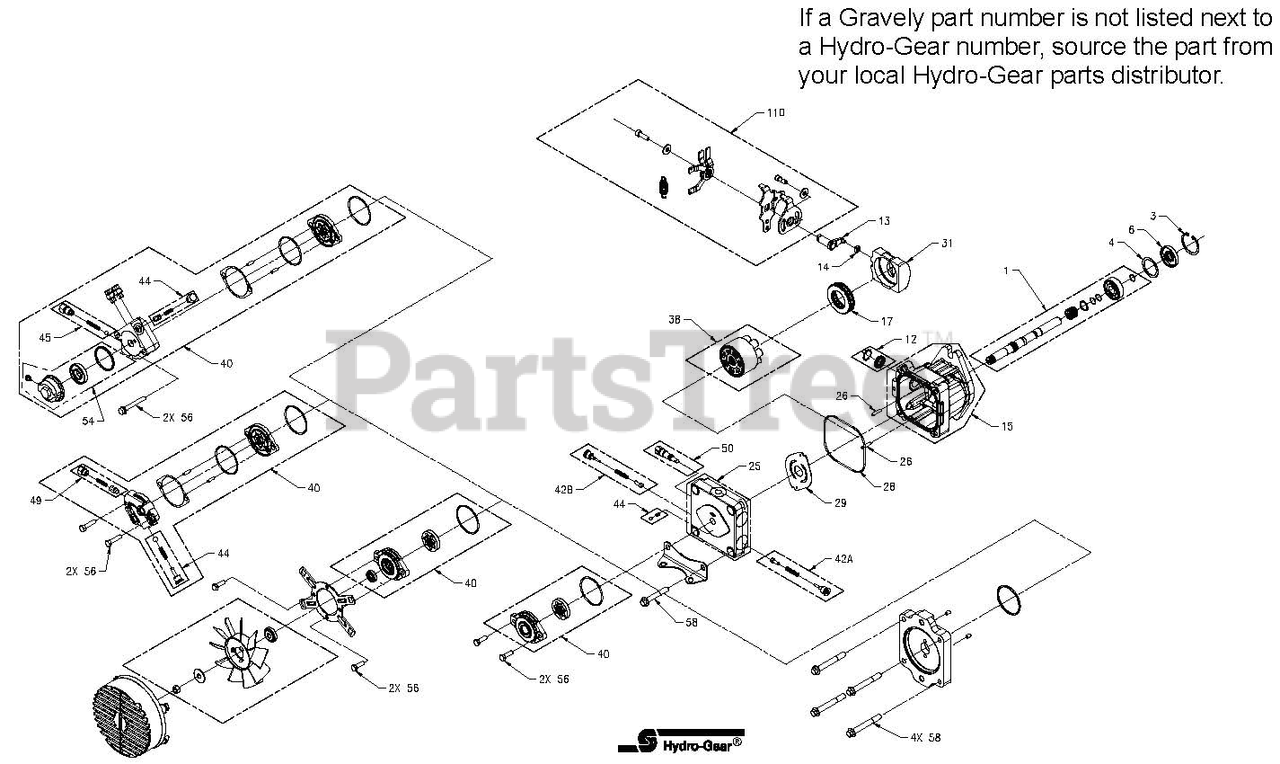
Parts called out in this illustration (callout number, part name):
1	Kit, Input Shaft
3	Ring, Retaining
4	Washer, 1.45 x 1.84 x .04
6	Lip Seal, 17 x 47 x 8
12	Kit, Trunnion Seal
13	Trunnion Arm, Taper Square
14	Slot Guide
15	Kit, Housing
17	Assembly, Thrust Ball Bearing
25	Kit, Encap
26	Pin
28	O-Ring
29	Valve Plate
31	Variable Swashplate
38	Kit, Cylinder Block
40	Kit, Auxiliary Pump
42	Kit, Shock Valve
44	Kit, Charge Relief
45	Kit, Auxilary Relief Valve
49	Kit, Auxilary Bypass/Check Kit
50	Kit, Bypass Valve
54	Kit, Auxilary Filter Kit
56	Screw, 5/16-18 x 1
58	Kit, HSG Bolt
110	Kit, Return
NS	Kit, Overhaul Seal Kit
